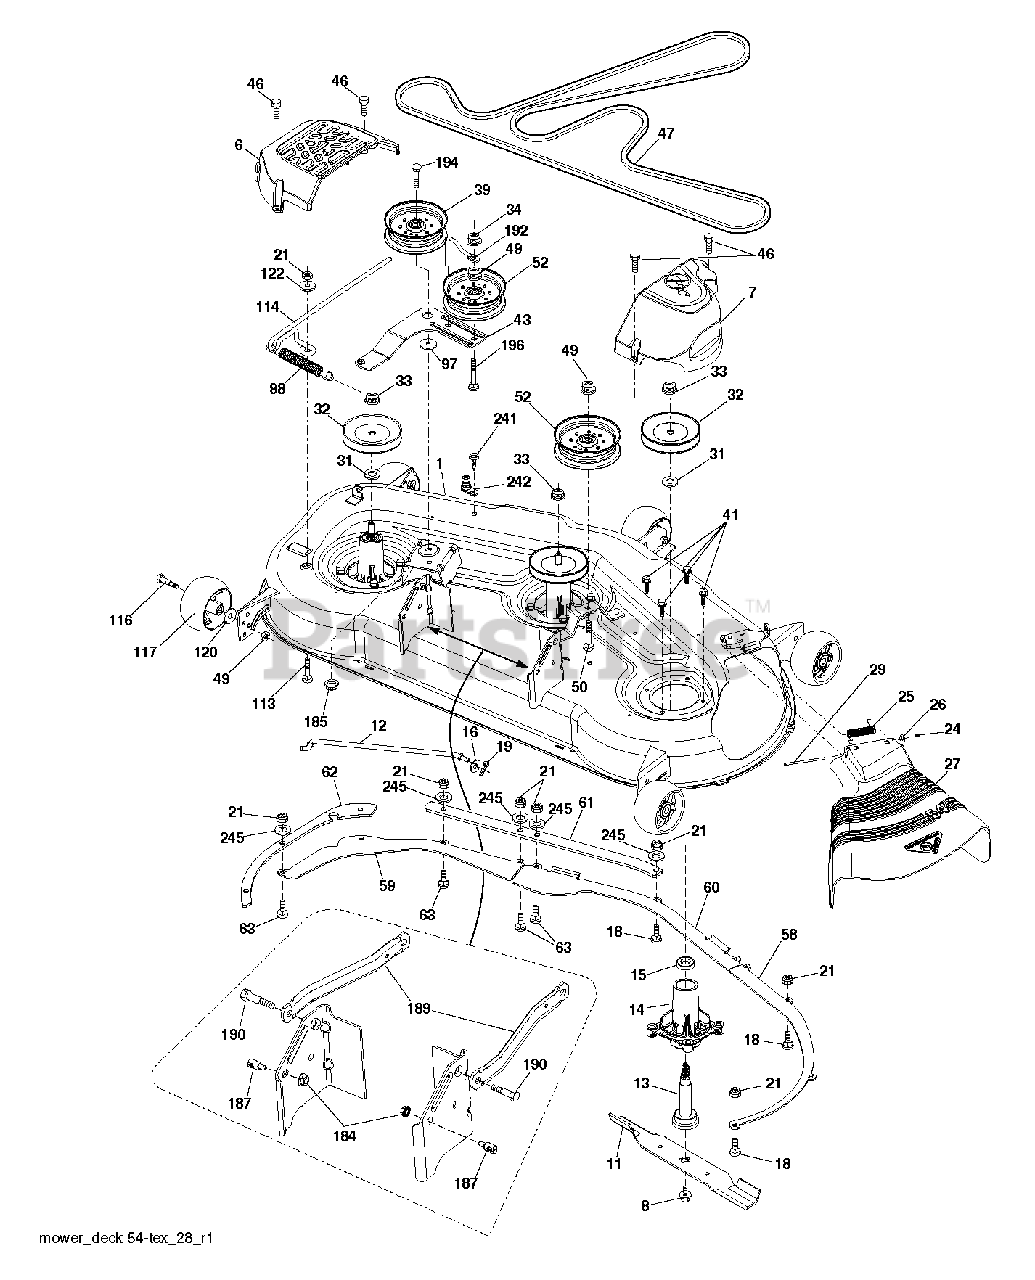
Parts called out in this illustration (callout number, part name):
1	DECK.SVC.54"
6	COVER.MANDREL.LH.54"20
7	COVER.MANDREL.RH.54.20
8	BOLT.WASHER.ASM.7/16-2
11	BLADE.BAGGING.54"
12	LINK.ASM.LIFT.54"TG
13	SHAFT ASM MANDREL
14	HOUSING.MANDREL.4PT.
16	WASHER
18	BOLT
19	PIN.COTTER.5/16.BOW TI
21	LOCKNUT
24	CAP-SLEEVE LT
25	SPRING, TORSION
26	NUT PUSH M
29	ROD.HINGE
31	WASHER.SPACER.MANDREL
32	PULLEY/MANDREL
33	NUT.FLANGE.LOCK.TOP
34	LOCKNUT
39	PULLEY.IDLER.4.50/HUB SPECIAL
41	Hex Washer Head Bolt, .313-18 X 1.19
43	ARM.IDLER
46	SCREW.1/4-20X5/8
47	BELT.DRIVE.54."2006
49	NUT LOCK FLG 3/8-16 UNC
50	BOLT
52	PULLEY.IDLER.2006
58	BAFFLE.RIGHT.54"
59	BAFFLE.LEFT.54"
60	BAFFLE CENTER 54" MOWER
61	Front Bolt Reinforcement Plate, 54" X 431
62	Side Bolt Reinforcement Plate, 54" X 431
63	BOLT.CARRIAGE.5/16-18
98	SPRING, DECK DRIVE
113	BOLT CRT
114	ROD TENSION RELIEF
116	BOLT.SHOULDER.3/8-16X3-5/8.
117	WHEEL. GUAGE RALLY
122	BUSHING.RELIEF.TENSION
184	NUT LOCK HEX FLANGE 5/16-18
185	NUT.LOCK.FLANGE.7/16
187	STUD.FASTNER.W/ANTI-ROTATE
189	ARM.SUSPENSION.MOWER
190	BOLT.SHOULDER
192	KEEPER.BELT.IDLER.54"T
194	BOLT.HEX.WASHER.HEAD.7/16-24X
196	BOLT
241	SCREW.TT.#10-32X.5.3/8.FLANGE
242	PORT.WASHOUT
245	WASHER
